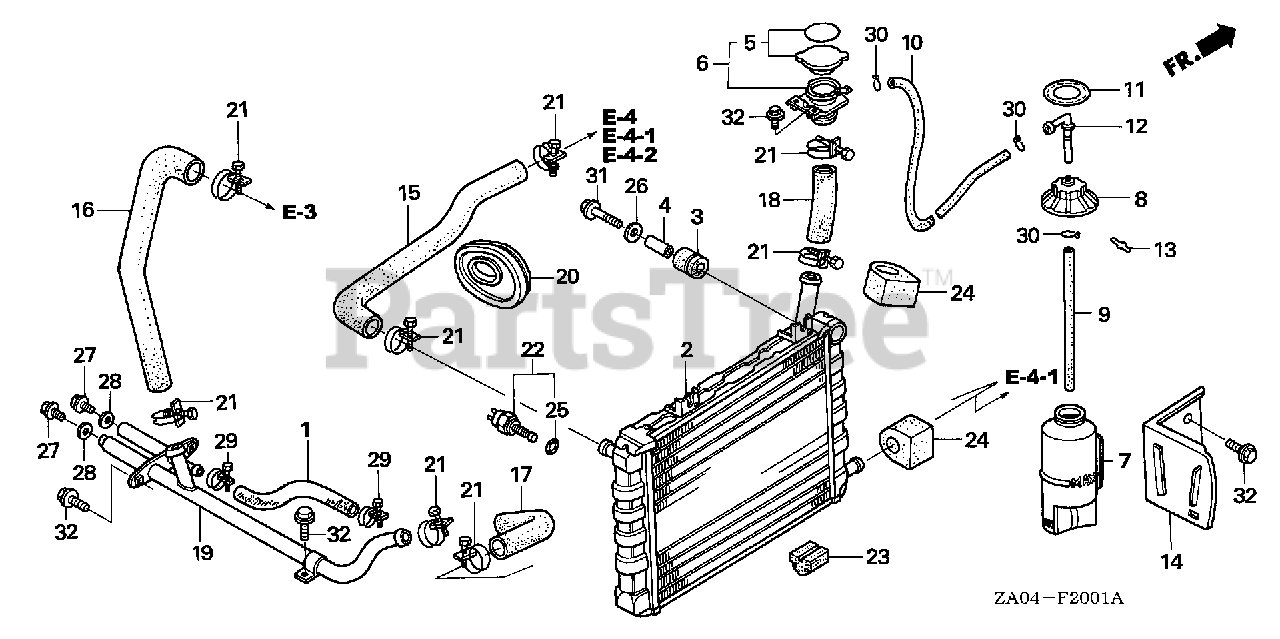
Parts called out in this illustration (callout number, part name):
1	TUBE, OIL DRAIN
2	RADIATOR (TOYO)
3	RUBBER, RADIATOR MOUNTING
4	COLLAR, DISTANCE (NOT AVAILABLE)
5	CAP, RADIATOR (DENSO)
6	PIPE, RADIATOR
7	TANK, RESERVE
8	CAP, RESERVE TANK
9	HOSE, RESERVE TANK
10	TUBE, RESERVE TANK
11	MARK, RESERVE TANK
12	JOINT, RESERVE TANK
13	CLIP, RESERVE TANK JOINT
14	SUPPORT, RESERVE TANK
15	HOSE, WATER (UPPER)
16	HOSE, WATER (LOWER)
17	HOSE B, WATER
18	HOSE A, WATER
19	PIPE, OIL & WATER DRAIN
20	GROMMET, WATER HOSE
21	CLIP, WATER HOSE
22	SWITCH, THERMOSTAT
23	RUBBER, RADIATOR MOUNTING
24	RUBBER B, SEPARATOR SEAL
25	O-RING (13.5X1.4)
26	WASHER, WHEEL (6MM)
27	BOLT, DRAIN PLUG (12MM)
28	WASHER, DRAIN PLUG (12MM)
29	CLIP, TUBE (A16)
30	CLIP, TUBE (C11)
31	BOLT, FLANGE (6X28)
32	BOLT, FLANGE (6X10)
